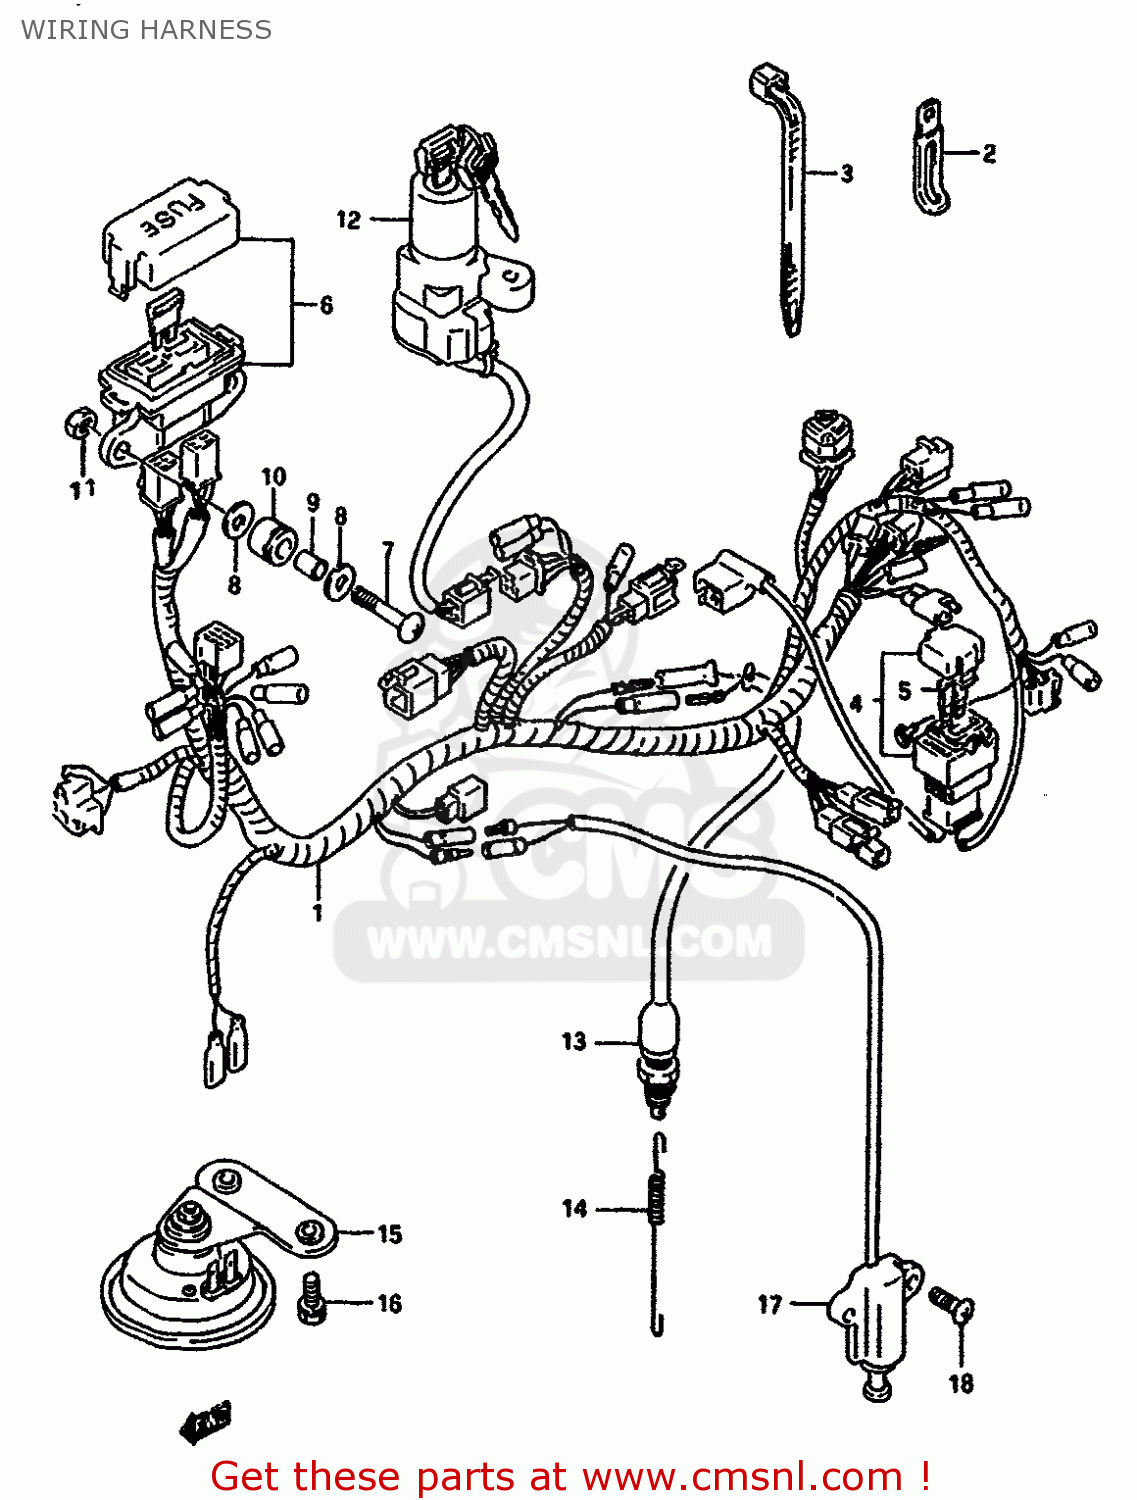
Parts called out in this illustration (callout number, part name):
1	HARNESS,WIRING
2	CLAMP
3	CLAMP(L:125)
4	BOX ASSY,FUSE
5	FUSE(15A)
6	FUSE ASSY
7	SCREW
8	WASHER(6.5X18X1)
9	SPACER
10	CUSHION 8X18X17.5
11	NUT
12	LOCK ASSY,STEERING
13	SWITCH ASSEMBLY,STOP LAMP
14	SPRING
15	HORN ASSY
16	BOLT
17	SWITCH ASSY,SIDE STAND WARNING
18	SCREW
